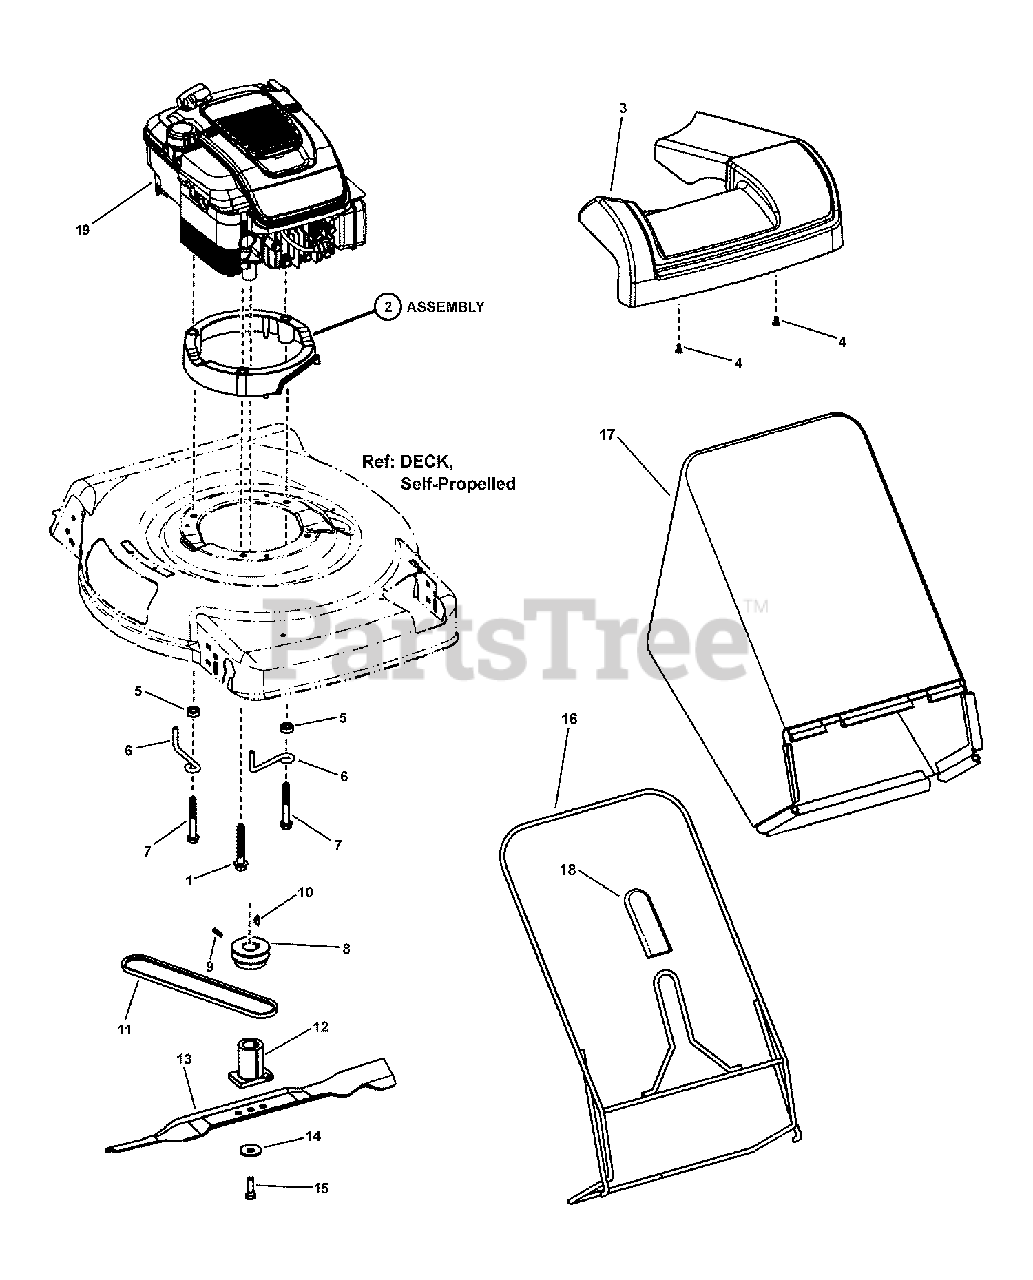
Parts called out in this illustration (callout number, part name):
1	BOLT, 3/8-16 NS x 2-1/2"
2	ASSEMBLY, Engine Spacer, 22" WBM, Self-Propelled
3	FRONT COVER, Deck, 22" Front Wheel Drive
4	SCREW, 4.8 x 1.59 x 13mm, Round Washer Head Hi-Lo (Torx)
5	SPACER, Belt Guide 22"
6	BELT GUIDE, Engine, 22"
7	SCREW, 3/8-16 x 3" Hex Washer Self-Tap
8	PULLEY, Engine
9	SET SCREW, 5/16-18 x 1/2" Hex Recess
10	KEY, #HP-506 HI-PRO
11	** BELT, Drive (3L Section; 31.94" effective length)
12	BLADE HUB, 22" Deck, Self Propelled
13	BLADE, 22", Walk Mower
14	WASHER, .38" I.D. x 1.183 O.D. Bellville
15	BOLT, 3/8-24 x 3-1/4" Hex Head, GR 8
16	BAG FRAME, 22" WBM (weldment)
17	GRASS BAG, 22" Rear Discharge
18	GRIP, Rectangular (Black)
19	* ENGINE, B&S, 650 Ser, X-Spec
19	* ENGINE, B&S, 675 Ser, X-Spec
